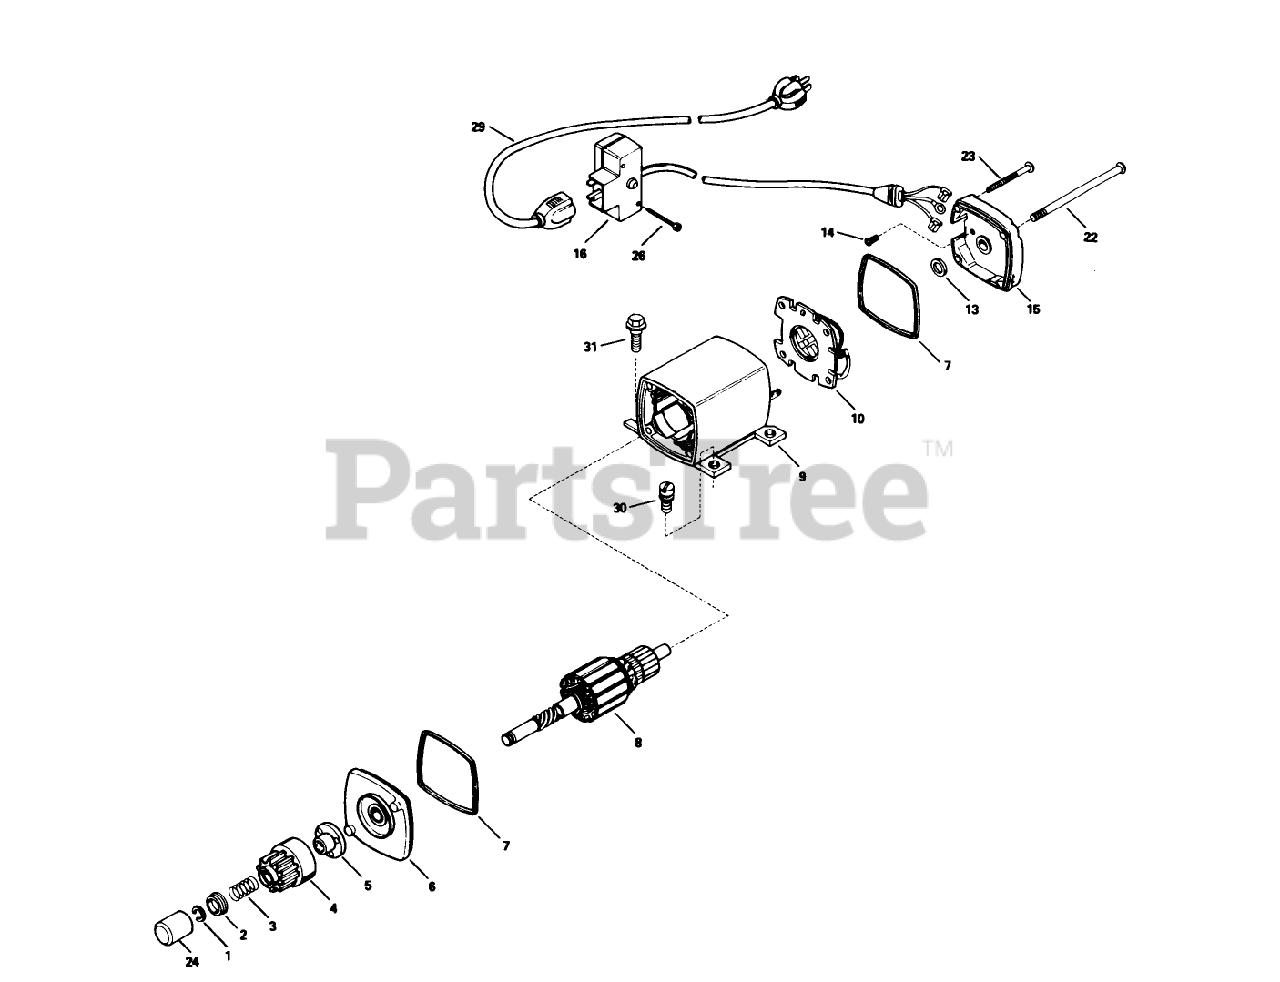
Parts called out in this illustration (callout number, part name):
1	Ring-Retainer
2	Retainer-Spring
3	Spring-Anti Drift
4	Gear
5	Nut-Engaging
6	Cap Assembly-Cap End (Incl. Ref. #7)
7	O-Ring
8	Armature
9	Housing Assy.
10	Card ASM
13	Washer-Thrust
14	Screw-Ground
15	Cap Assembly (Incl. Ref. #7)
16	Box Assembly-Switch (Incl. Ref. #26)
22	Bolt-Case
23	Screw-Ground
24	Cover-Dust
26	Screw
29	Cord-Extension
30	Screw
31	Screw (1/4-20x1/2)
